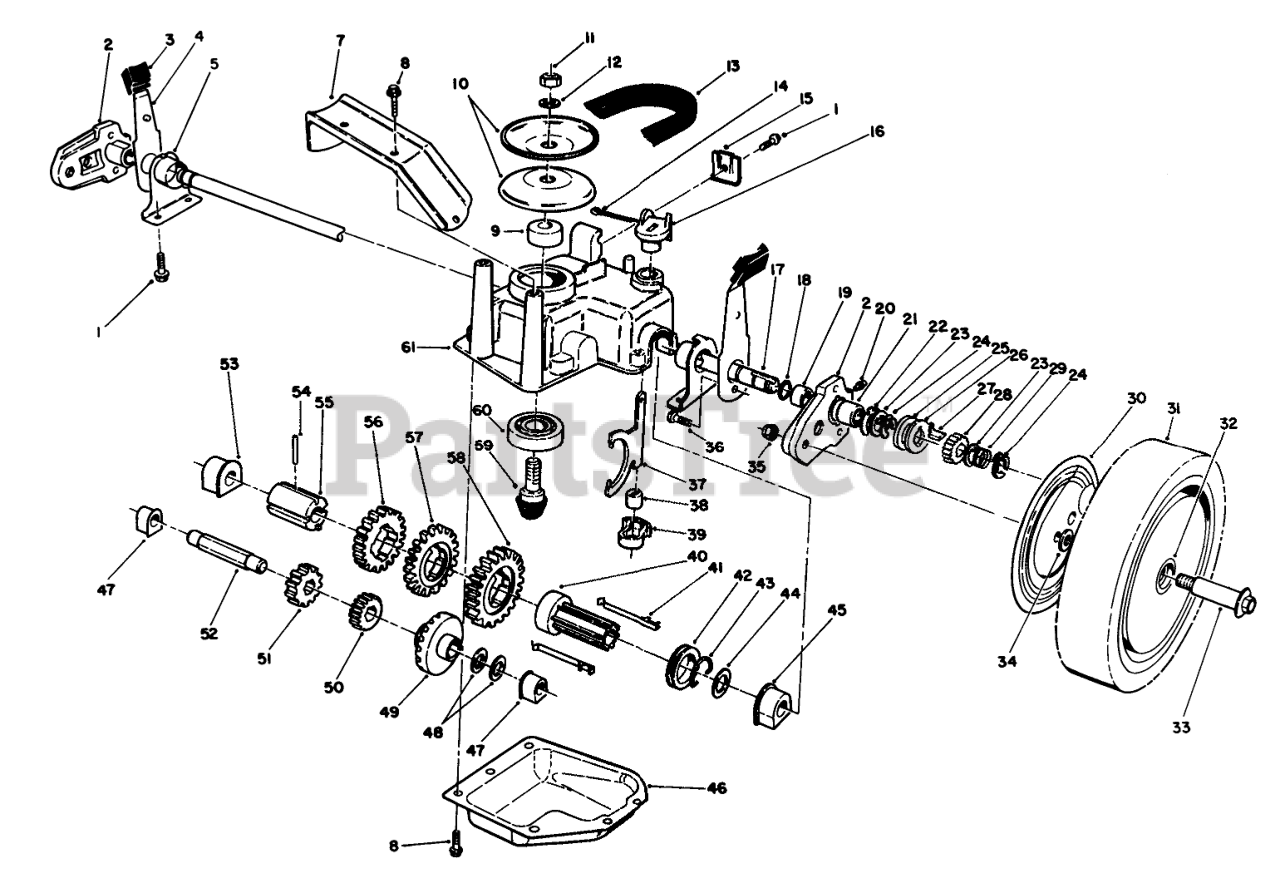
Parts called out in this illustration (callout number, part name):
1	SCREW-HWHTF
2	Pivot Arm Assembly (Incl. Ref. #19-21)
3	KNOB-ARM
4	SPRING ARM ASM
5	CAP-END
7	Bracket-BeltGuide
8	SCREW-HWHTF
9	SPACER
10	Pulley Half
11	NUT-HEX
12	WASHER-FLAT
13	V-BELT
14	PIN-COTTER
15	CABLE CLAMP
16	Lever-Shift
17	SHAFT-OUTPUT
18	O-RING
19	BUSHING
20	FITTING-GREASE
21	BEARING-ROLLER
22	WASHER-ARM, PIVOT
23	WASHER-THRUST, KEYED
24	RING-CLIP, LOCKING
25	RING-FRICTION
26	WASHER-CLUTCH
27	KEY-ROCKING, LH
28	GEAR-PINION
29	SPRING-COMPRESSION
30	WHEEL COVER
31	Wheel Tire & Gear Assy. (Incl. Ref. #32)
32	BUSHING
33	WHEEL BOLT
34	WASHER
35	Nut
36	SCREW-HSH, THREAD FORMING
37	YOKE-SHIFT
38	BUSHING-YOKE
39	RETAINER-FORK, SHIFT
40	Sleeve-Shift Key
41	SHIFT KEY
42	SHIFT COLLAR
43	CLIP-SPRING
44	WASHER-PLAIN
45	BUSHING-OUTPUT
46	Cover-Gearcase
47	BUSHING
48	WASHER-THRUST
49	Gear-Bevel
50	PINION-20T
51	PINION-25T
52	SHAFT-INTERMEDIATE
53	BUSHING
54	PIN-SPRING
55	SLEEVE-GEAR
56	GEAR-39T
57	GEAR-44T
58	GEAR-49T
59	Gear-Pinion
60	BEARING-BALL
61	CASE-GEAR, UPPER
